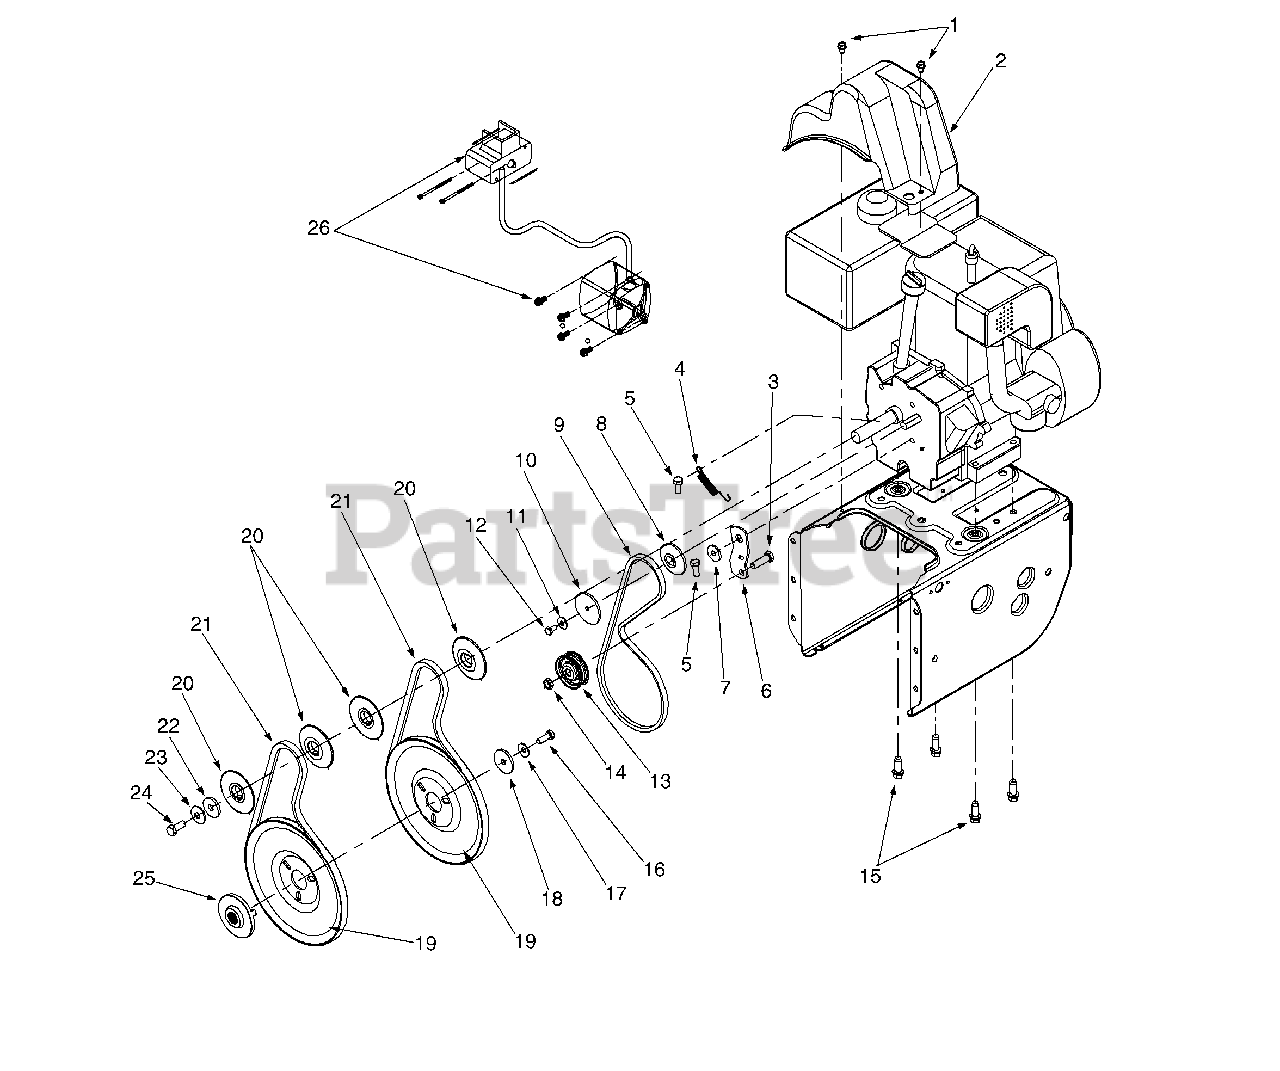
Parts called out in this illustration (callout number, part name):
1	Hex Washer Screw 1/4-20 x .50
2	Belt Cover
3	Hex Cap Screw 3/8-16 x 1.25
4	Spring Extension
5	Hex Screw 5/16-24 x .75
8	Pulley Half
9	Belt
10	Pulley Half
11	Bell Washer
12	Hex Cap Screw
13	Flat Idler
14	Lock Jam Nut 3/8-16
15	Hex Washer Screw 3/8-16 x 1.0
16	Hex Lock Screw 5/16-24 x .875
17	Bell Washer .340 ID x .872 OD
18	Flat Washer .341 ID x .50 OD
19	Pulley Auger
20	Pulley Half
21	V-Belt
22	Flat Washer
23	Bell Washer .39 ID x 1.13 OD
24	Hex Cap Screw 3/8-24 x .875
25	Pulley Adapter
26	Electric Start
